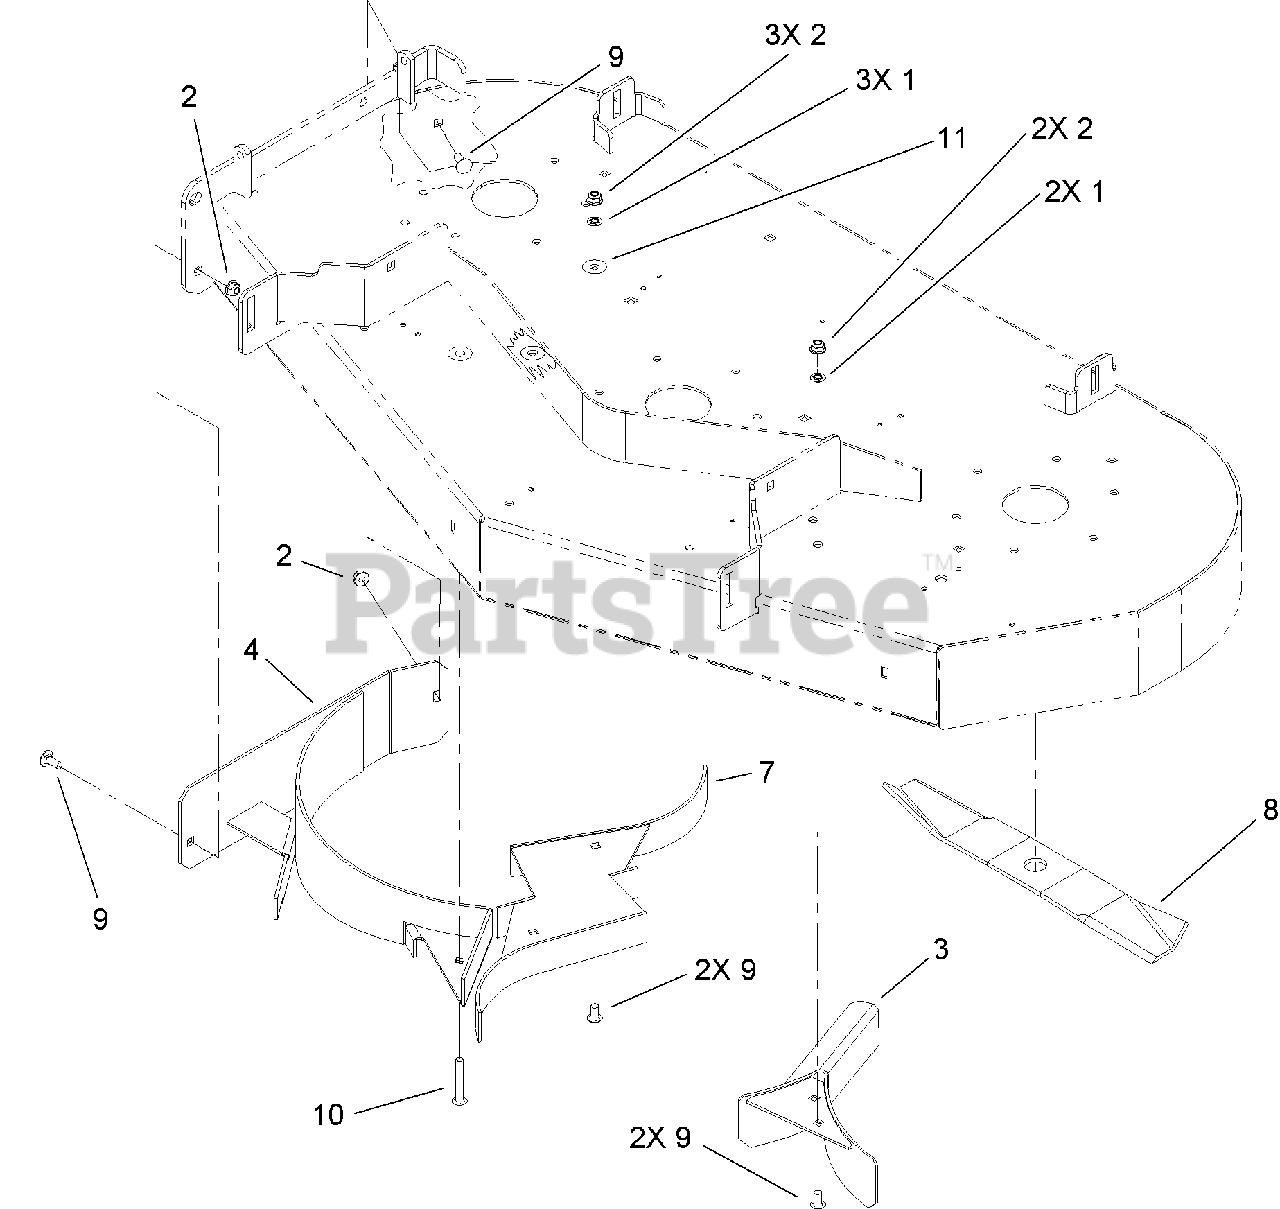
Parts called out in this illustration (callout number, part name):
1	RING-BOLT RETAINING
2	NUT-FLANGE, NI
3	LH MULCH BAFFLE ASM
4	RH MULCH BAFFLE ASM
7	CENTER BAFFLE ASM
8	BLADE-MULCH
9	SCREW-CARR
10	SCREW-CARR
11	DECAL-HOLE COVER
